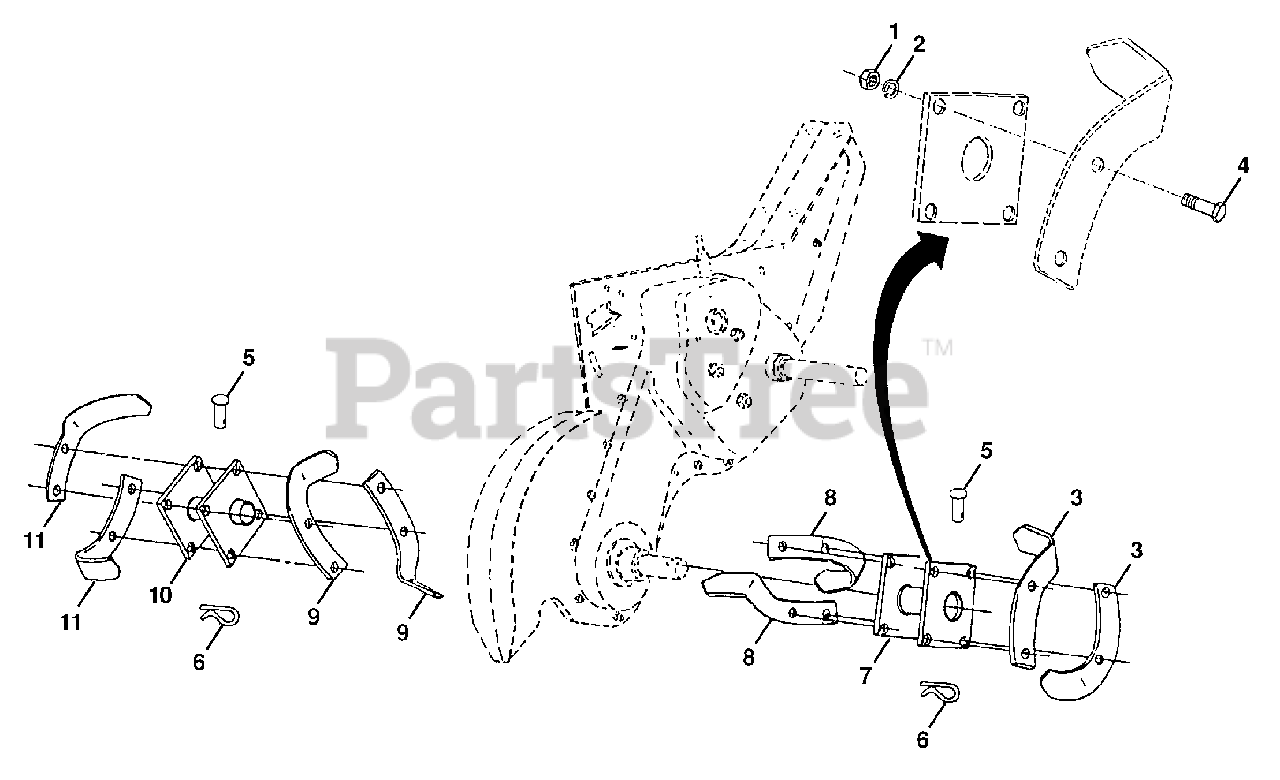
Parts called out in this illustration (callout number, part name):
1	Nut, Hex 3/8-24
2	Washer, Lock 3/8
3	Tine, Outer, R. H.
4	Bolt, Hex 3/8-24 x 1
5	Pin, Shear
6	Clip, Hairpin
7	Assembly, Hub and Plate, R.H.
8	Tine, Inner, R. H.
9	Tine, Inner, L. H.
10	Assembly, Hub and Plate, L.H.
11	Tine, Outer, L. H.
